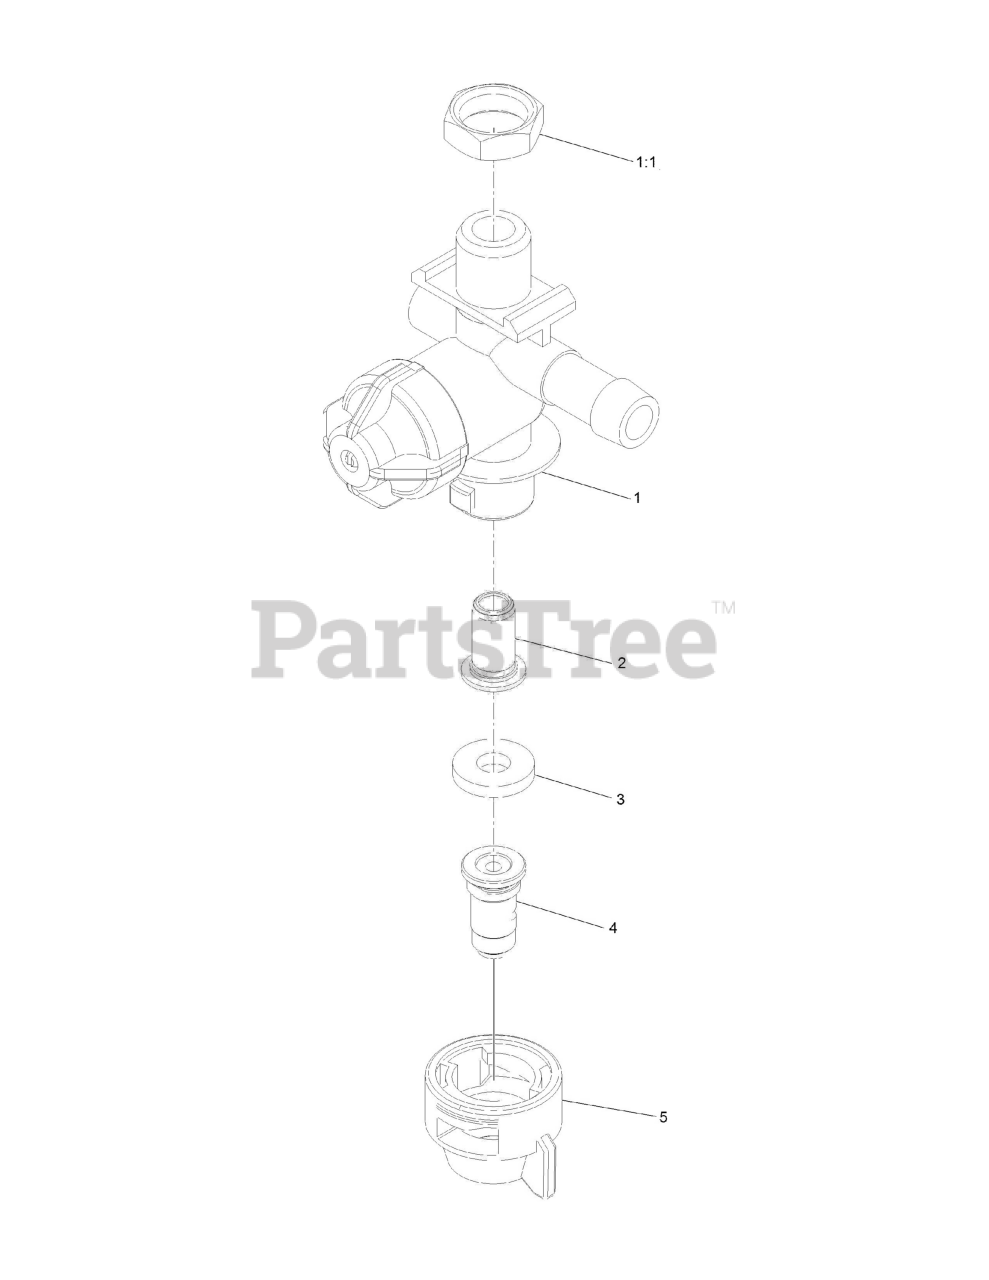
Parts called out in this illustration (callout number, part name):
1	LH NOZZLE BODY ASM
1:1	NUT-NYLON
2	STRAINER-TIP
4	NOZZLE-SPRAY, WHITE
